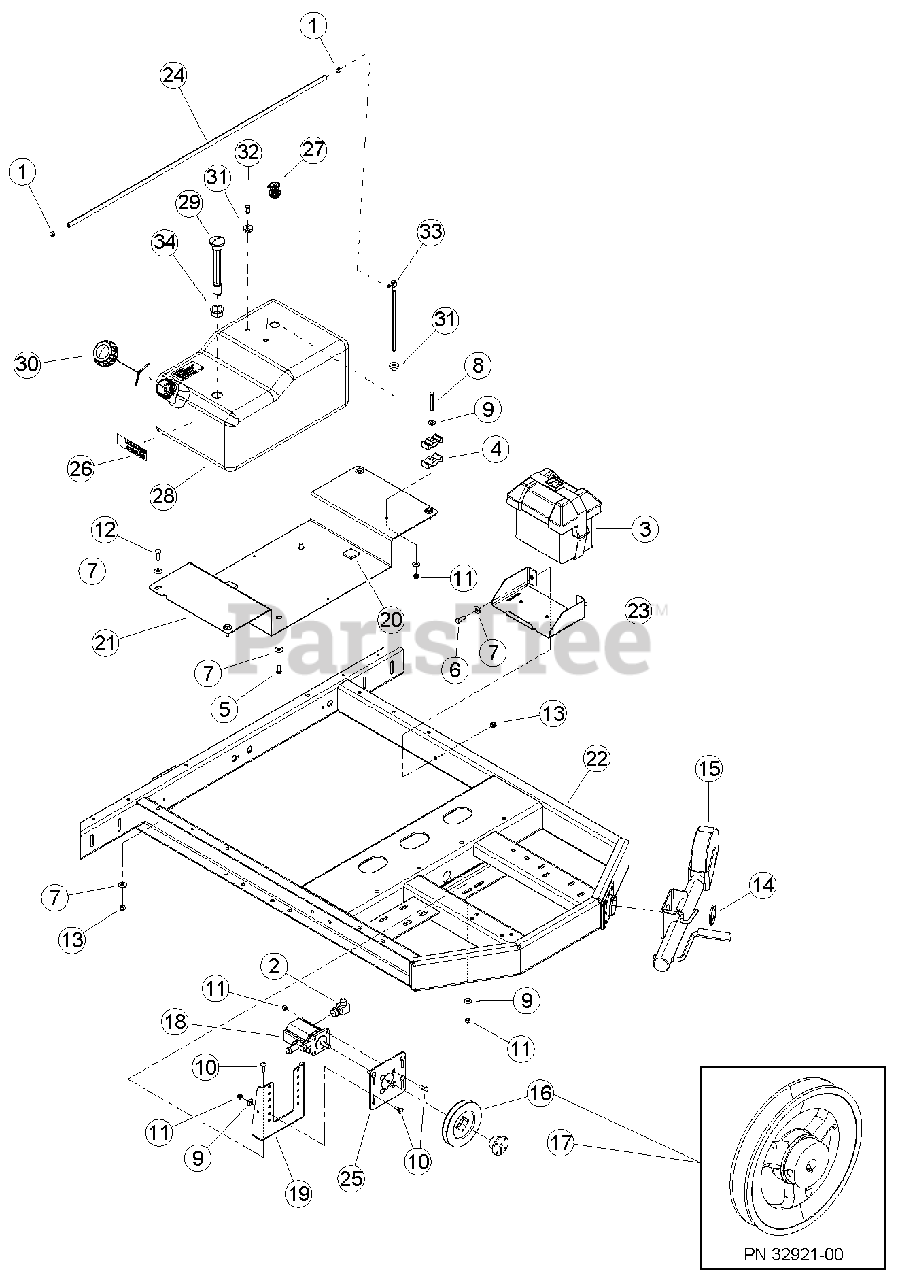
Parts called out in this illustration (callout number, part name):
1	CLAMP, HOSE 5/16 X 5/8 DIA. MAX
2	ADAPTER, -10 MORING / -8 MJIC 90 DEG.
3	BOX, SMALL BATTERY
4	CLAMP, PLASTIC HOSE
5	BOLT, 3/8 X 3/4 HEX HD GR5 ZP
6	BOLT, 3/8 X 1 HEX HD GR5 ZP
7	WASHER, 3/8 FLAT ZP
8	BOLT, 5/16 X 2-1/2 HEX HD GR5 ZP
9	WASHER, 5/16 FLAT ZP
10	BOLT, 5/16 X 1 CRG GR5 ZP
11	NUT, 5/16 NE NYLOCK ZP
12	BOLT, 3/8 X 1-1/4 HEX GR5 ZP
13	NUT, 3/8 NE NYLOCK ZP
14	SNAP RING, 2-1/2 EXTERNAL
15	JACK, PIVOTING W/SWIVEL CASTOR
18	PUMP, 2 STAGE CW HI/LO 0.605 DISP.
19	BRACKET, MOUNT HYDRAULIC PUMP
20	PAD, FOAM FUEL TANK DAMPER
21	BASE, 9.5 GAL NYLON TANK
22	WELDMENT, CHIPPER TRAILER
23	BRACKET, BATTERY HOLDER
24	HOSE, 63" FUEL LINE 1/4" DIA
25	PLATE, HYDRAULIC PUMP
26	DECAL, UNLEADED GASOLINE
27	VALVE, ROLL OVER
28	TANK, ROTOMOLDED FUEL
29	GAUGE, FUEL LEVEL KELCH 100
30	CAP, NON-VENTED EPA/CARB APPROVED
31	GROMMET, TANK FITTING
32	PLUG, TANK VENT
33	FITTING, TANK FUEL PICK-UP TUBE
34	GROMMET, KELCH 100 GAUGE
